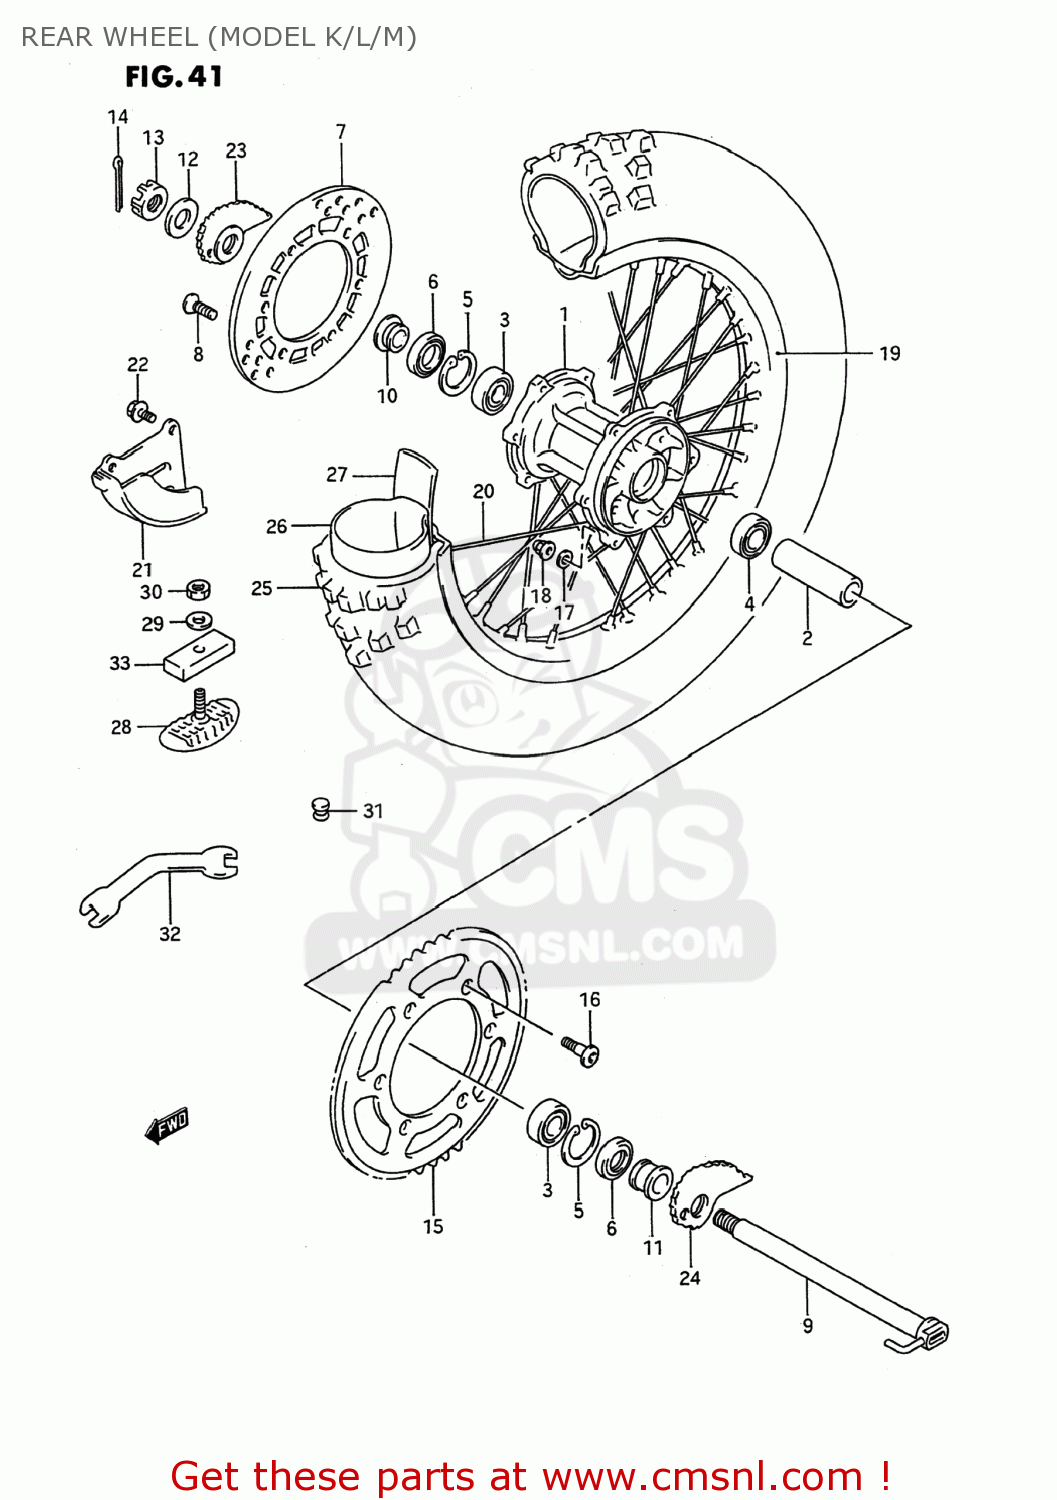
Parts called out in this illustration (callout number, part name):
1	HUB,RR
2	SPACER,RR HUB BEARING
3	BEARING WHEEL REAR(20X47X14)
4	BALL BEARING
5	CIRCLIP,14MM
6	SEAL,OIL(26X47X5)
7	DISC,REAR BRAKE
8	SCREW
9	AXLE,RR
10	SPACER,RR AXLE,R
11	SPACER,RR AXLE,L
12	WASHER (19X32X3.2)
13	NUT 18MM
14	PIN,COTTER
15	SPROCKET,REAR
16	SCREW(8X33.5)
17	WASHER
18	NUT
19	RIM,REAR WHEEL (2.15X18)(A
20	SPOKE ASSY,RR WHEEL
21	COVER COMP,REAR BRAKE
22	BOLT
23	ADJUSTER,CHAIN,R
24	ADJUSTER,CHAIN,L
25	TIRE,REAR 110/100-18
26	TUBE,INNER
27	PROTECTOR,INNER TUBE
28	STOPPER,BEAD
29	WASHER
30	NUT
31	CAP(OD:12)
32	SPANNER,OPEN
33	CUSHION,BEAD STOPPER
